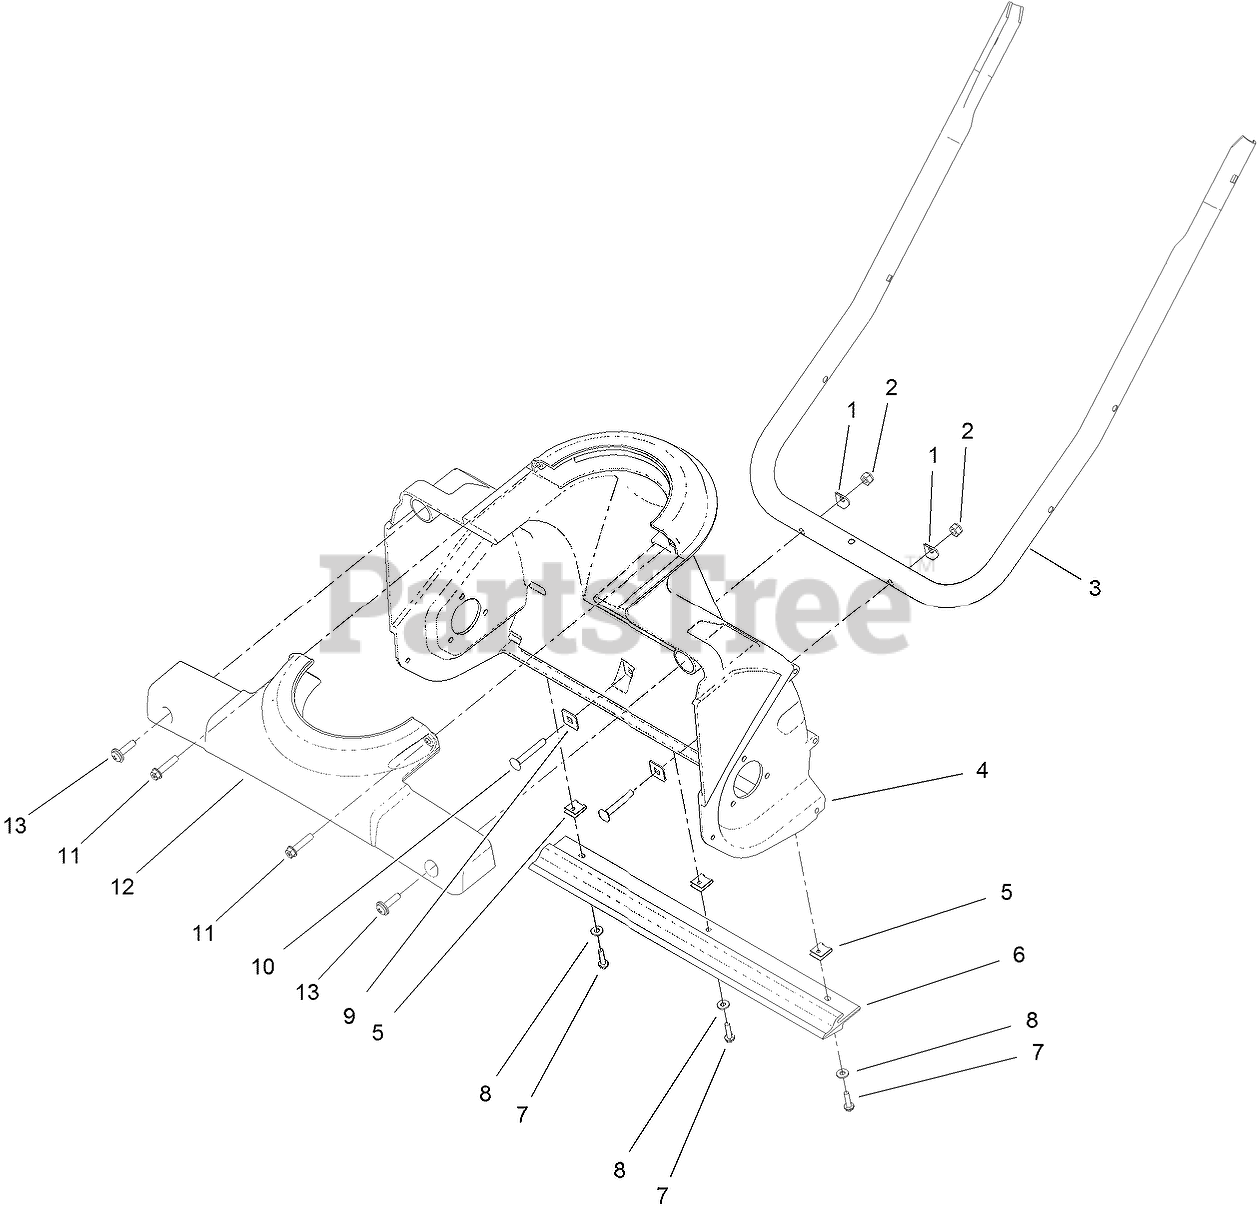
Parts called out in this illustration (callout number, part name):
1	WASHER
2	NUT-HEX
3	HANDLE-LOWER
4	HOUSING-LOWER
5	NUT-CLIP, U
6	SCRAPER
7	SCREW-THD FORM,HWH
8	WASHER-PLAIN
9	WASHER-SQUARE
10	BOLT-CARR
11	SCREW-PLASTIC,HWH
12	RETAINER-CHUTE
13	SCREW-PPH, SEMS
